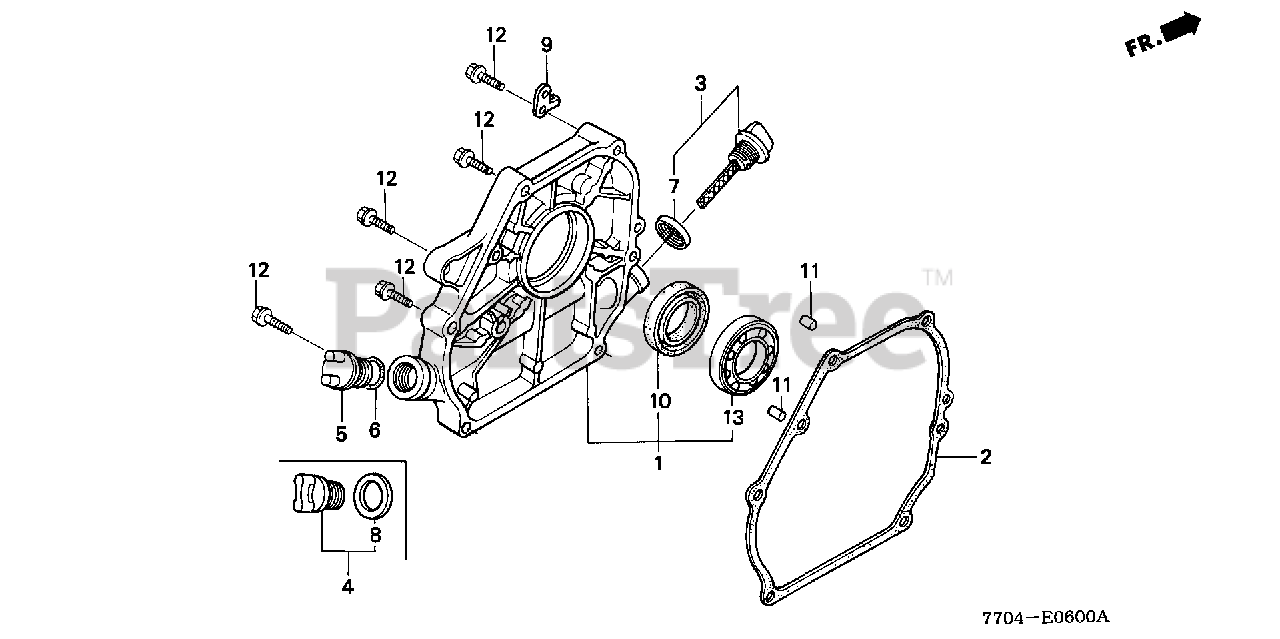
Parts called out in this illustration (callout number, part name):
1	COVER ASSY., CRANKCASE
2	GASKET, CASE COVER (NON-ASBESTOS)
3	CAP ASSY., OIL FILLER (GRAY)
4	CAP ASSY., OIL FILLER
7	GASKET, OIL FILLER CAP
8	GASKET, OIL FILLER CAP
9	STAY, WIRE CLIP (A)
10	OIL SEAL (25X41X6)
11	PIN, DOWEL (8X14)
12	BOLT, FLANGE (8X32)
13	BEARING, RADIAL BALL (6205)
